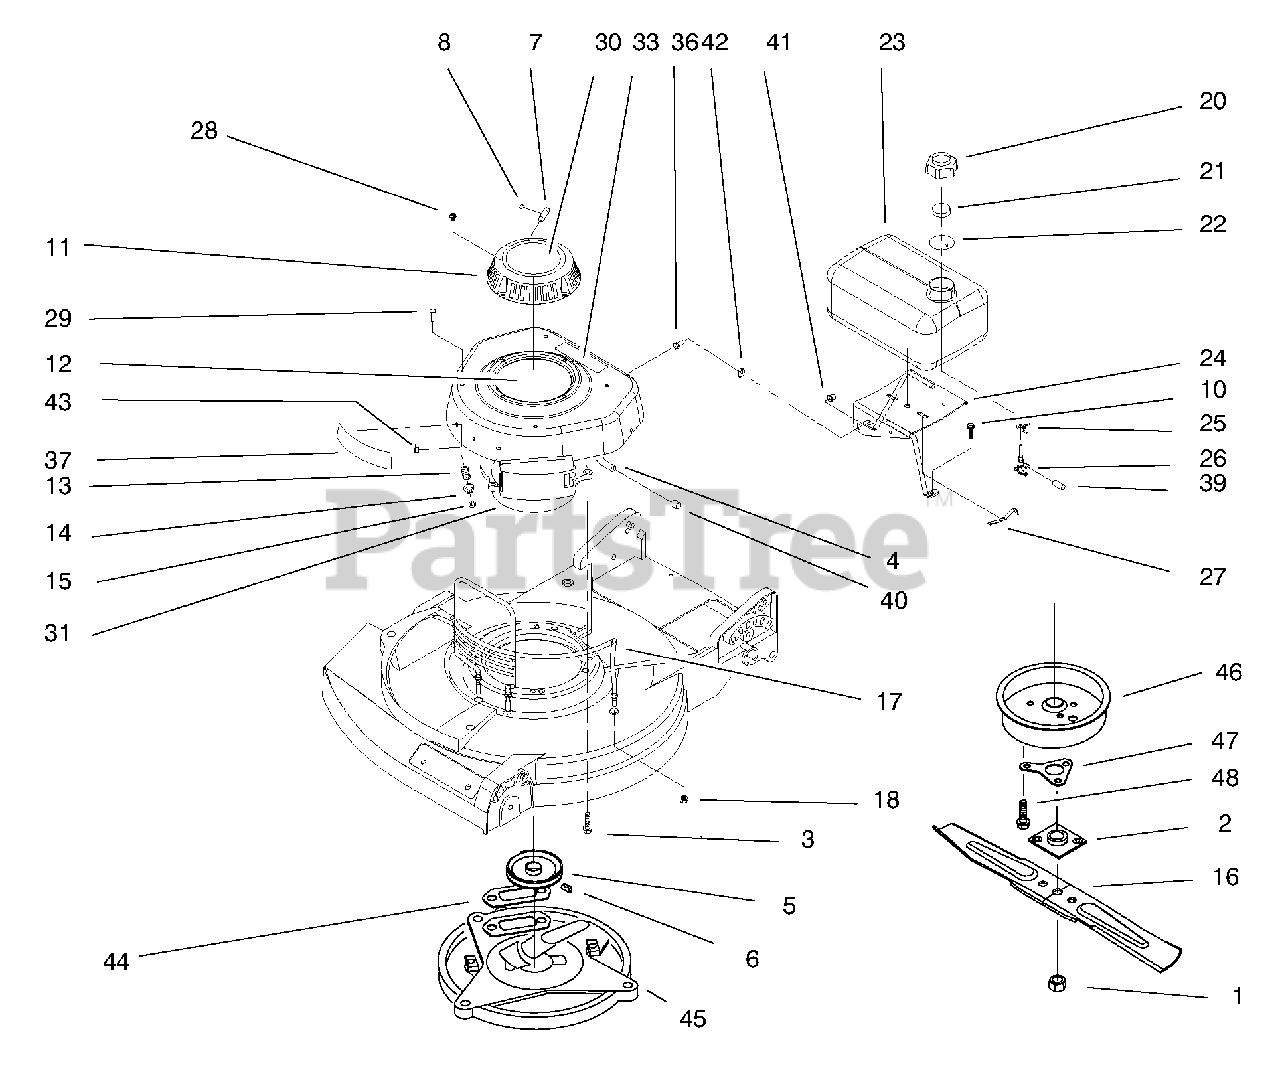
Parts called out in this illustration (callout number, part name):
1	Nut-Blade
2	Plate & Collar Assembly
3	Screw-Engine Mount
4	Hose-Gas
6	Screw-Set
7	Rope-Stop
8	Staple
10	Screw-Hex Washer Hd.
11	Housing-Starter
12	Shroud Assembly
14	Actuator-Brake Lever
15	Retainer
16	Blade-21"
17	Guard-Engine
18	Nut-Lock
20	Cap-Fuel
21	Foam-Baffle
23	Tank-Fuel
24	Leg & Saddle Assembly
25	Clamp-Hose
26	Valve & Screen
28	Screw-Sems
29	Screw-Thr'd Form
30	Decal-Recoil
31	Engine-2 Cycle
33	Decal-Oil
36	Screw-Carriage
37	Applique
39	Plug-Fuel Valve
40	Plug-Fuel Line
41	Nut-Lock
42	Washer-Flat
43	Retainer-Applique
44	Gasket-Muffler
45	Plate-Muffler
46	Muffler Cover Assembly
47	Support-Crankshaft
